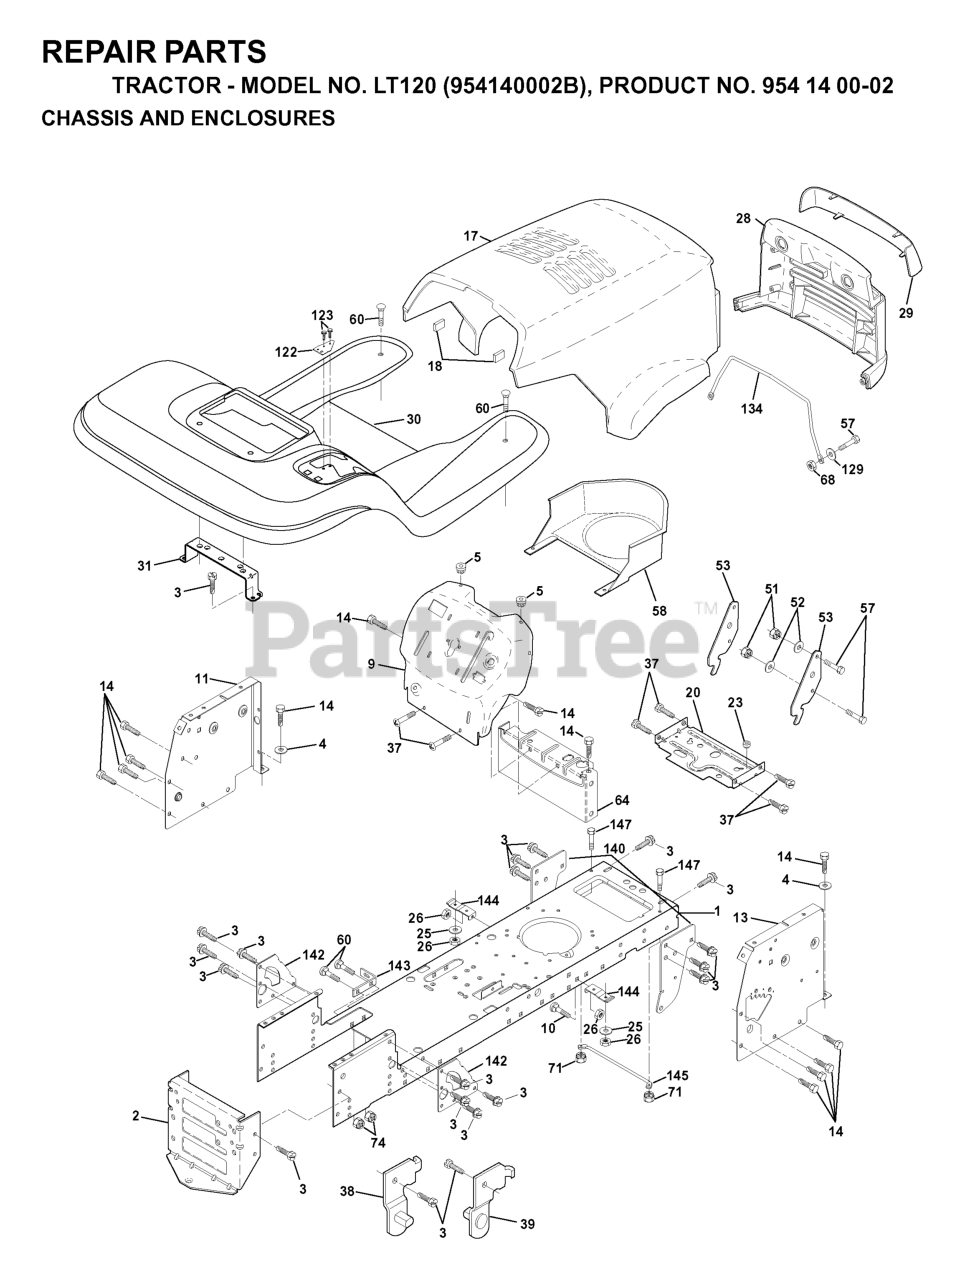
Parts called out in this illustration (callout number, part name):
1	CHASSIS WELDMENT
2	STRETCH DRAWBAR
3	SCREW
4	Washer 13/32 X 3/4 X 16 Ga.
5	BUMPER.RUBBER.HOOD
10	BOLT D
11	PANEL DASH LH
13	PANEL DASH RH
17	HOOD - LT/YT
18	BUMPER HOOD T
20	PLATE MTG
23	BUSHING.SNAP.NYL.BLK.
25	WASHER
26	NUT
28	GRILLE LT/PL HUSQVARNA
29	LENS LT/PL HUSQVARNA
30	FENDER FOOTREST
31	BRACKET.SUPPORT.FENDER
37	Screw 5/16-18 x 1/2 Hex, Self Tapping 5/16-18 x 1/2
38	BRACKET LH PIVOT
39	BRACKET RH PIVOT
51	LOCKNUT.NYLOC.1/4-20
53	BRACKET PNT PICK OFF LT/PL
57	BOLT
58	AIR DUCT P/L/LT
60	Bolt - Rd. Hd. Sq. Neckiage 3/8 16 x 3/4
64	DASH LOWER
68	NUT
71	NUT.CROWNLOCK.1/4
122	BRACKET SHIFT STLT
123	SCREW.TT.#10-32X.5.3/8.FLANGE
134	ROD SUPPORT HOOD LT/PL HUS.
140	BRACKET SUSPENSION FRONT
142	PLATE REINFORCEMENT
143	BRACKET, SWAY BAR
144	BRACKET FOOTREST
145	ROD PIVOT CHASSIS/HOOD
147	BOLT.HEX.1/4.X.3/4.DICHROMATE
